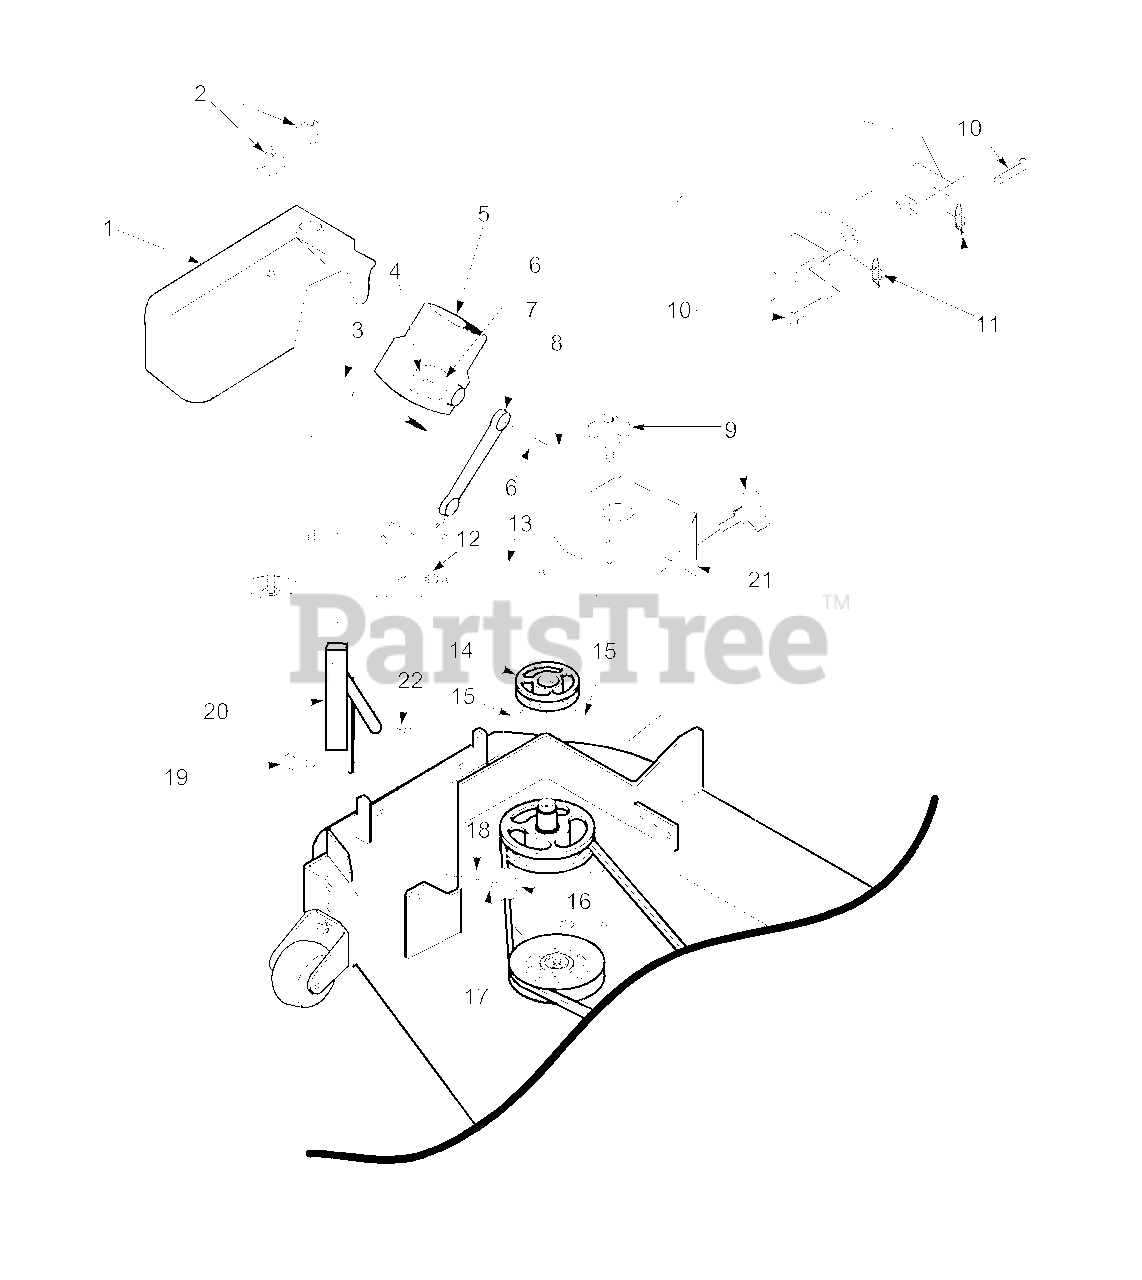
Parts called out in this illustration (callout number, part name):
1	Belt Cover, GC-STC
2	Wingnut, Plastic 3/8 Small
3	Cap, Square Vinyl
4	Nut, Elastic Stop 1/4-20
5	Adapter, Blower GC-STC
6	Flatwasher, 1/4-.312 x .750 x .065
7	Rubber Strap 7-3/4"
8	Bolt, Hex Head 1/4-20 x 1-1/4"
9	Knob W/Stud, 3/8-16 x 1-1/4"
10	Clevis Pin, 5/16 x 1-1/2"
11	Pin, Rue Cotter 5/16 Dia.
12	Pin, Ring 1/2 x 2-1/4"
13	Lanyard
14	Pulley, 3-3/4" for 48" Deck
15	Setscrew, 5/16-18 x 3/8"
16	Nut, Elastic Stop 3/8-16
17	Lockwasher, 3/8"
18	Flatwasher, 3/8-.391 x .938 x .105
19	Bolt, Carr. 3/8-16 x 1-1/4" Grade 5
20	Mounting Post Weldment, Blower
21	Belt Cover
